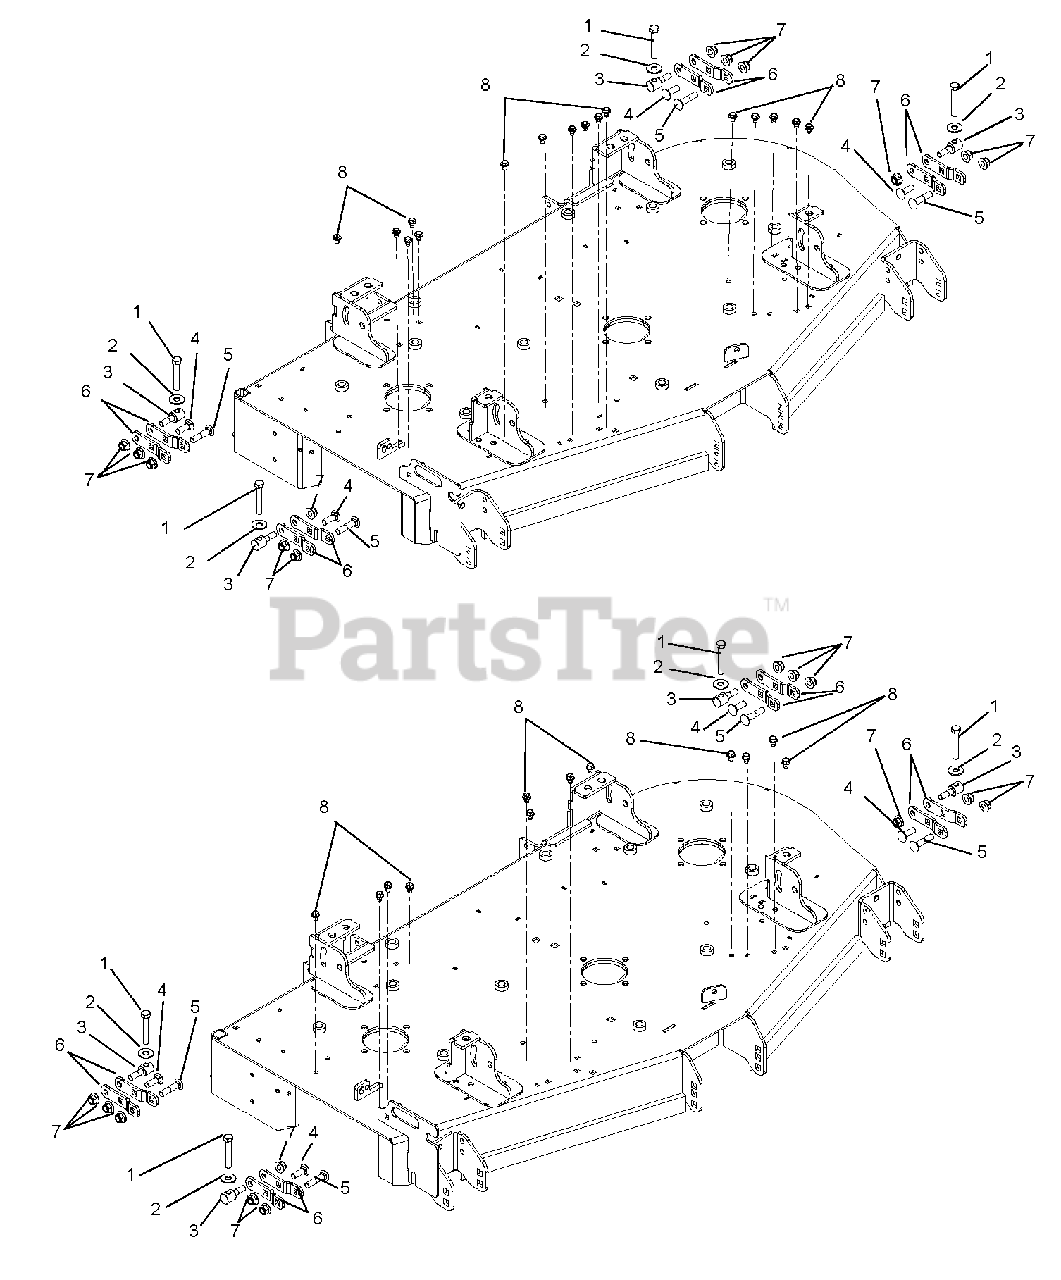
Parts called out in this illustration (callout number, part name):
1	Bolt, Hex .50-13 x 3.00 Grade 5 Full Thread
2	Washer, Flat Steel .563 x 1.38 x .109
3	Trunnion, .50-13
4	Bolt, Round Head Square Neck .50-13 x 1.50 Grade 5
5	Bolt, Round Head Square Neck .50-13 x 2.25 Grade 5
6	Deck Leveling Bracket – Black
7	Nut, Locking Nylon Flange .50-13
8	Screw, Tapping .38-16 x .50 Hex Washer Head
